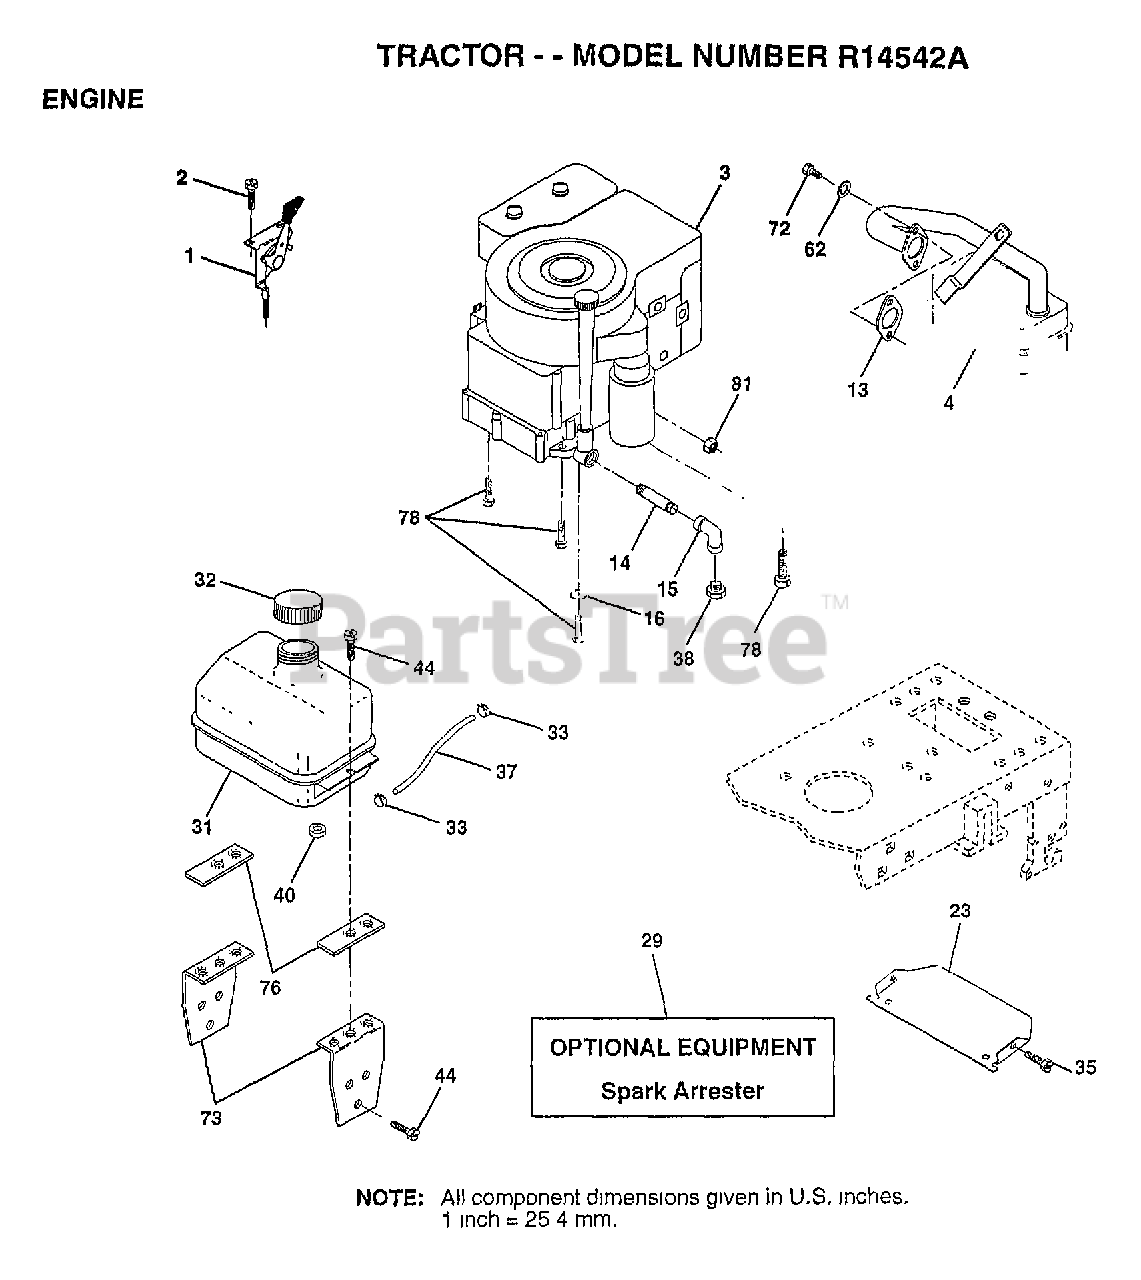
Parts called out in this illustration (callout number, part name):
1	THROTTLE CONTROL
2	SCREW LT
4	MUFFLER
13	GASKET ENG 1 313 LD TIN PLATED
14	PIPE NIPPLE
15	ELBOW
16	LOCKWASHER
23	SHIELD-HEAT
31	TANK.FUEL.LT.
32	CAP ASM FUEL
33	HOSE CLAMP
35	SCREW
37	LINE FUEL
62	LOCKWASHER
72	SCREW
73	BRKT FUEL TANK T
76	"CLAMP,FUEL TANK T"
78	SCREW
81	NUT
444	SCREW
